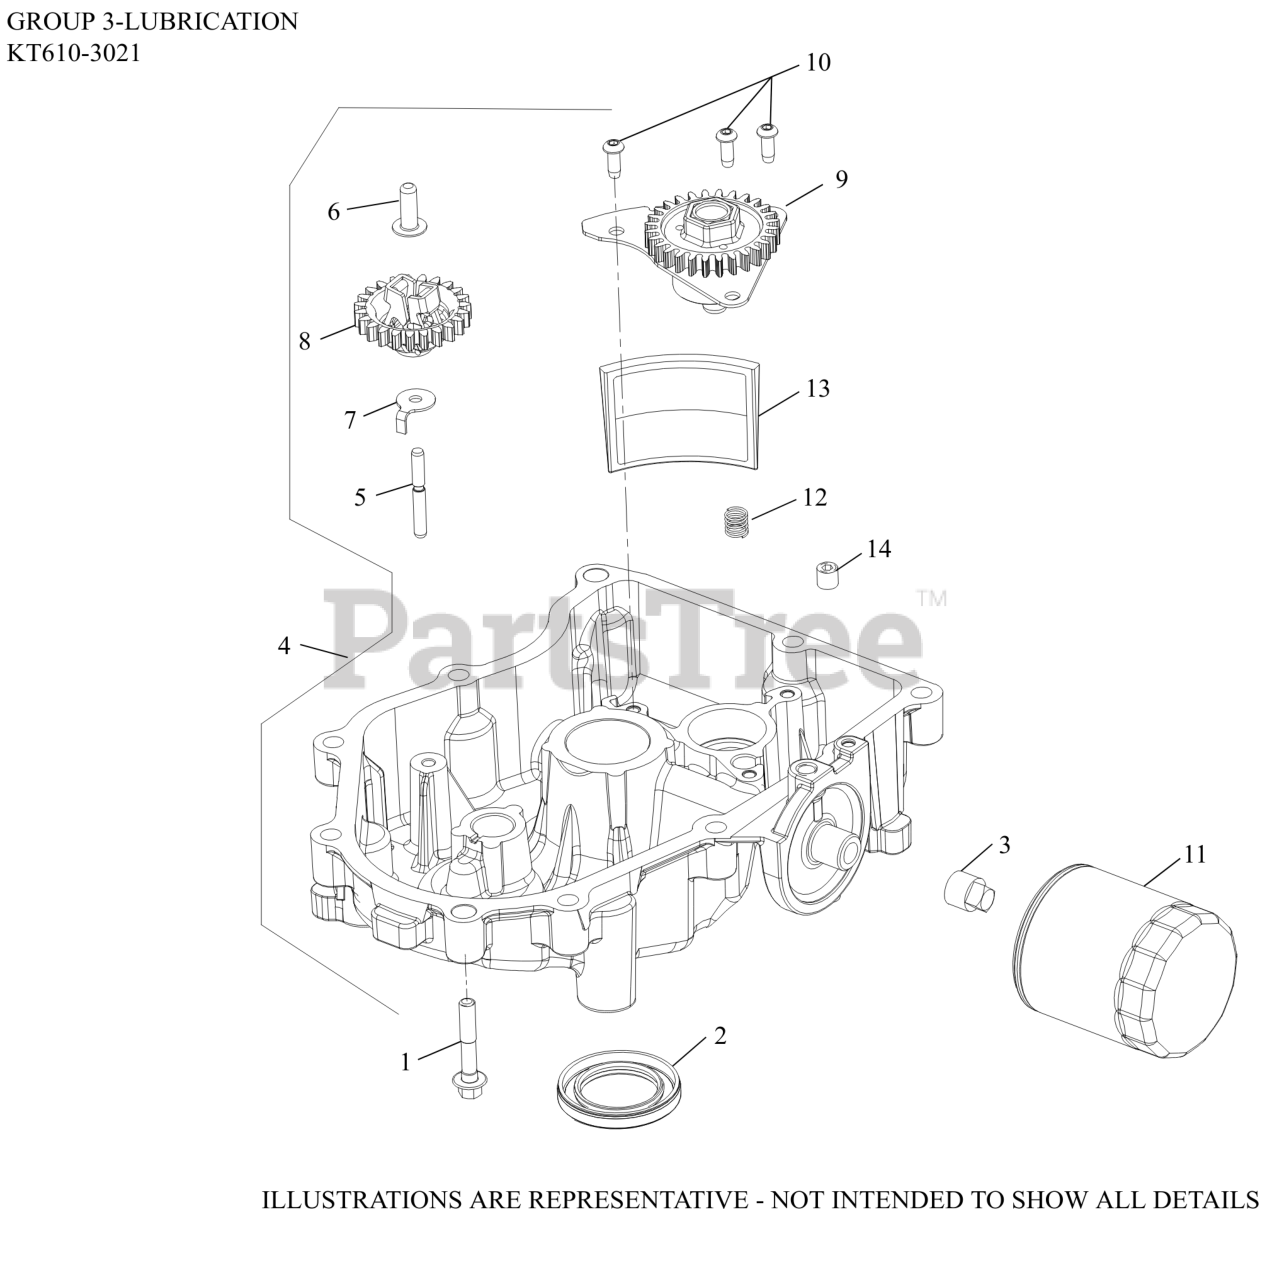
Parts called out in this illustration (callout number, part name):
1	SCREW, FLG M8X1.25X45
3	PLUG, SQ HD PIPE 3/8"
4	PAN ASSEMBLY, OIL-(#3219924S)
5	SHAFT, GOVERNOR GEAR
6	PIN, GOVERNOR REGULATING
7	TAB, LOCKING
8	KIT, GOVERNOR GEAR
9	PUMP ASSEMBLY, OIL
10	SCREW, BUTTON HEAD
11	OIL FILTER
12	SPRING, COMPRESSION
13	SCREEN, OIL
14	PLUG, CTSK PIPE 1/8"
